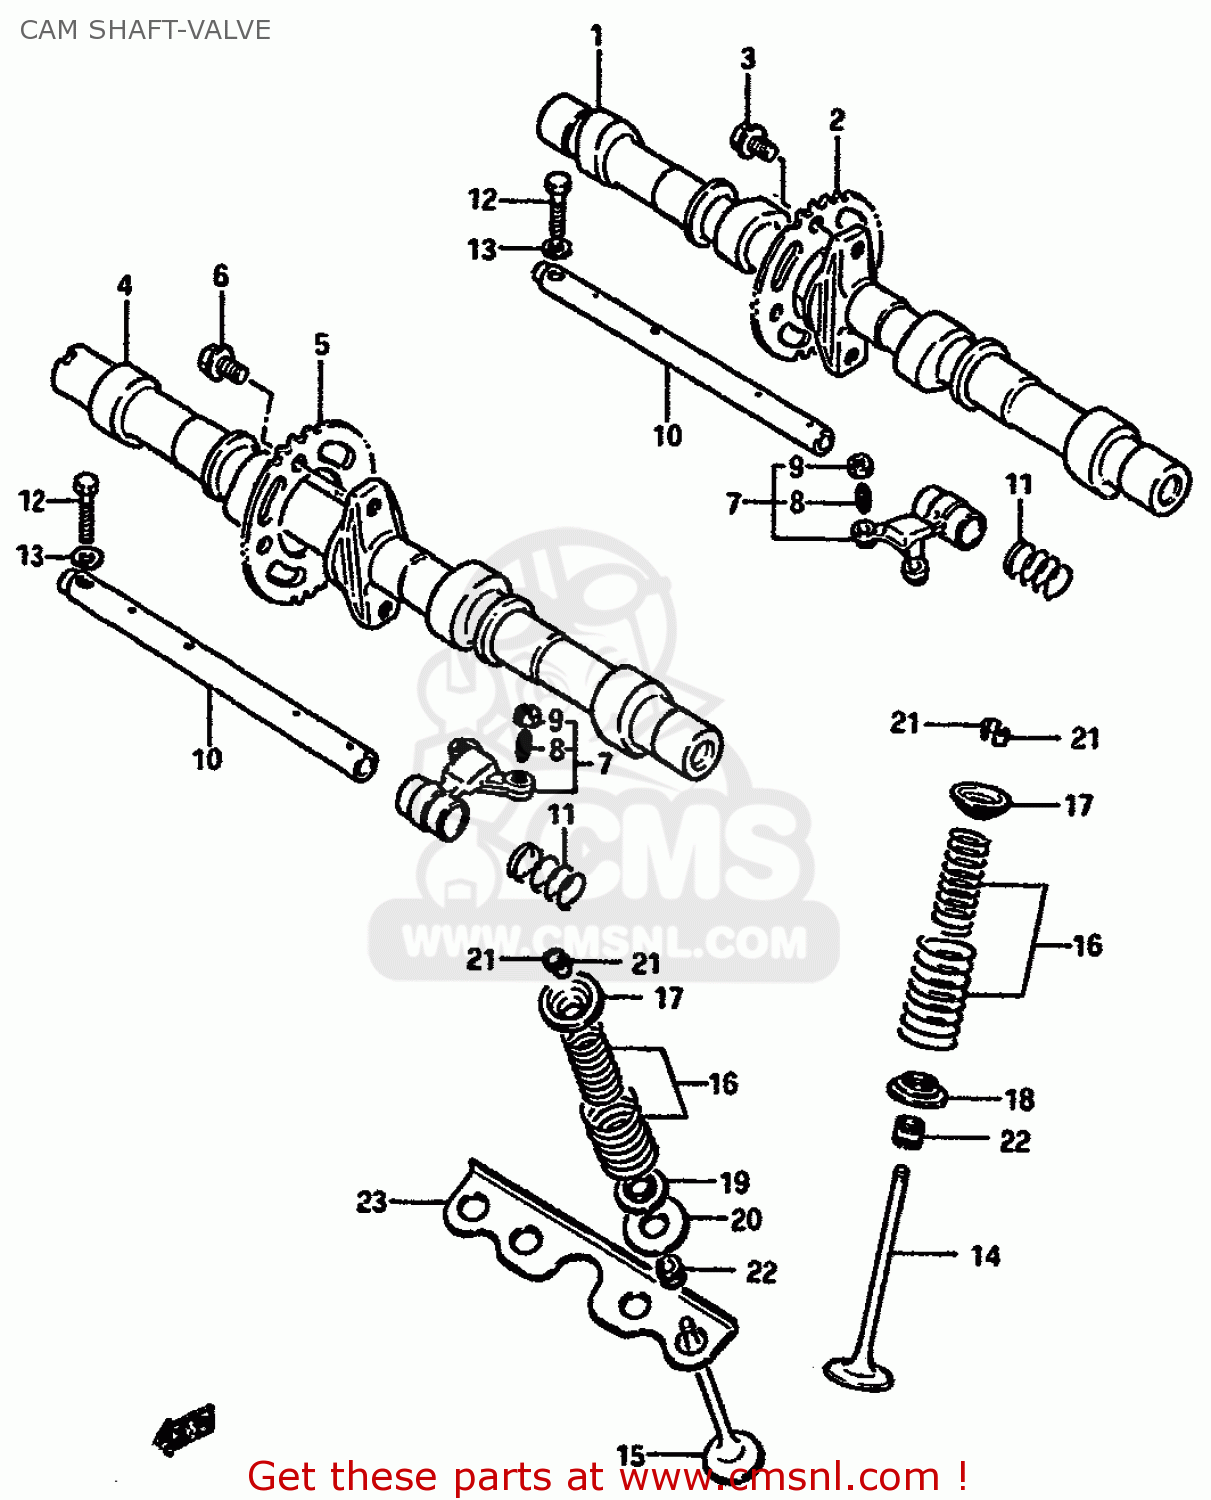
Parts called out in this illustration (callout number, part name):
1	CAMSHAFT
2	SPROCKET,CAMSHAFT
3	BOLT(7X11)
4	CAMSHAFT,EXHAUST
5	SPROCKET,CAMSHAFT
6	BOLT(7X11)
7	ARM,VALVE ROCKER
8	SCREW,TAPPET ADJUSTING
9	NUT,ADJUSTING
10	SHAFT,VALVE ROCKER ARM
11	SPRING
12	BOLT
13	WASHER, LOWER
14	VALVE,INTAKE
15	VALVE,EXHAUST
16	SPRING SET,VALVE
17	RETAINER,VALVE SPRING
18	SEAT,VALVE SPRING
19	SEAT,VALVE SPRING
20	SEAT,VALVE SPRING EXH OUTER
21	COTTER VALVE
22	OIL SEAL
23	PLATE
